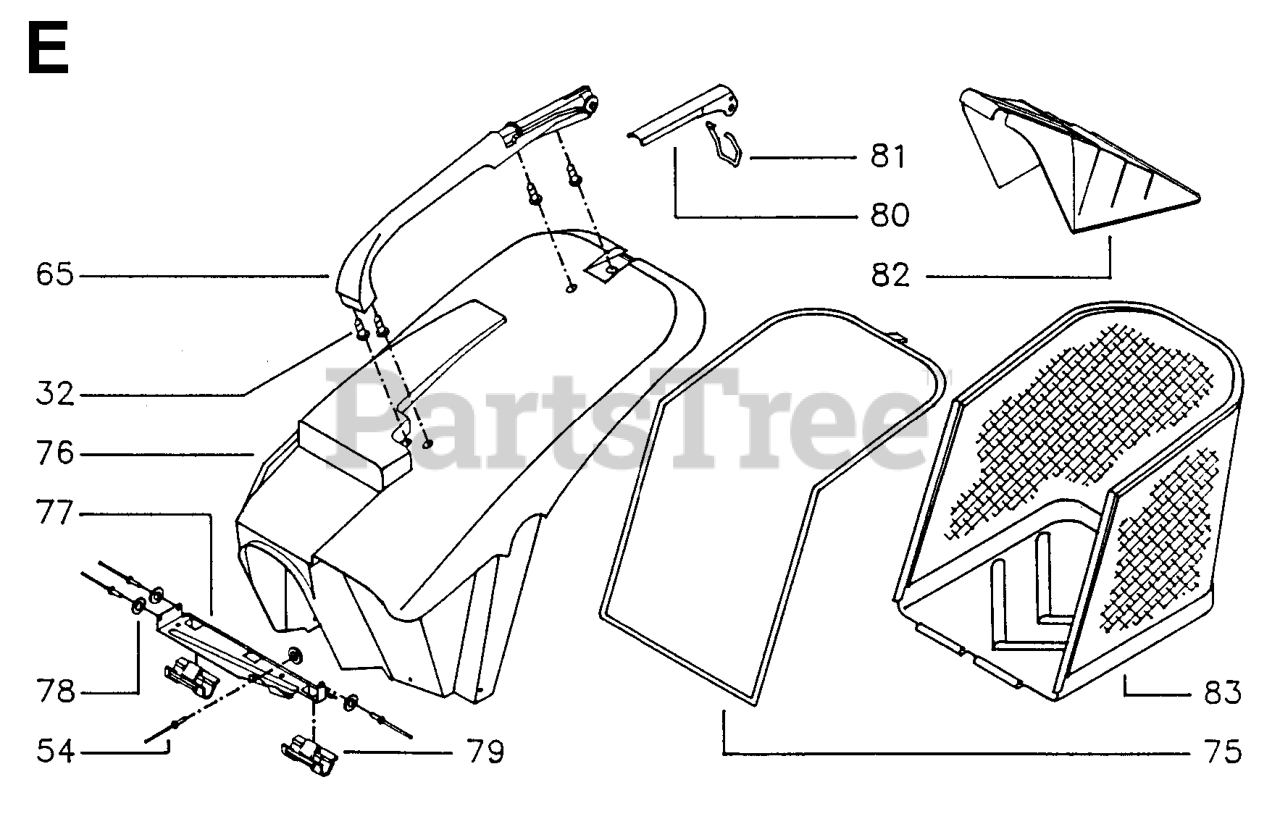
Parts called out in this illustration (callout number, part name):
32	SCREW
54	REPL BY 516 92 38-00
82	REPL BY 997 00 85-15
